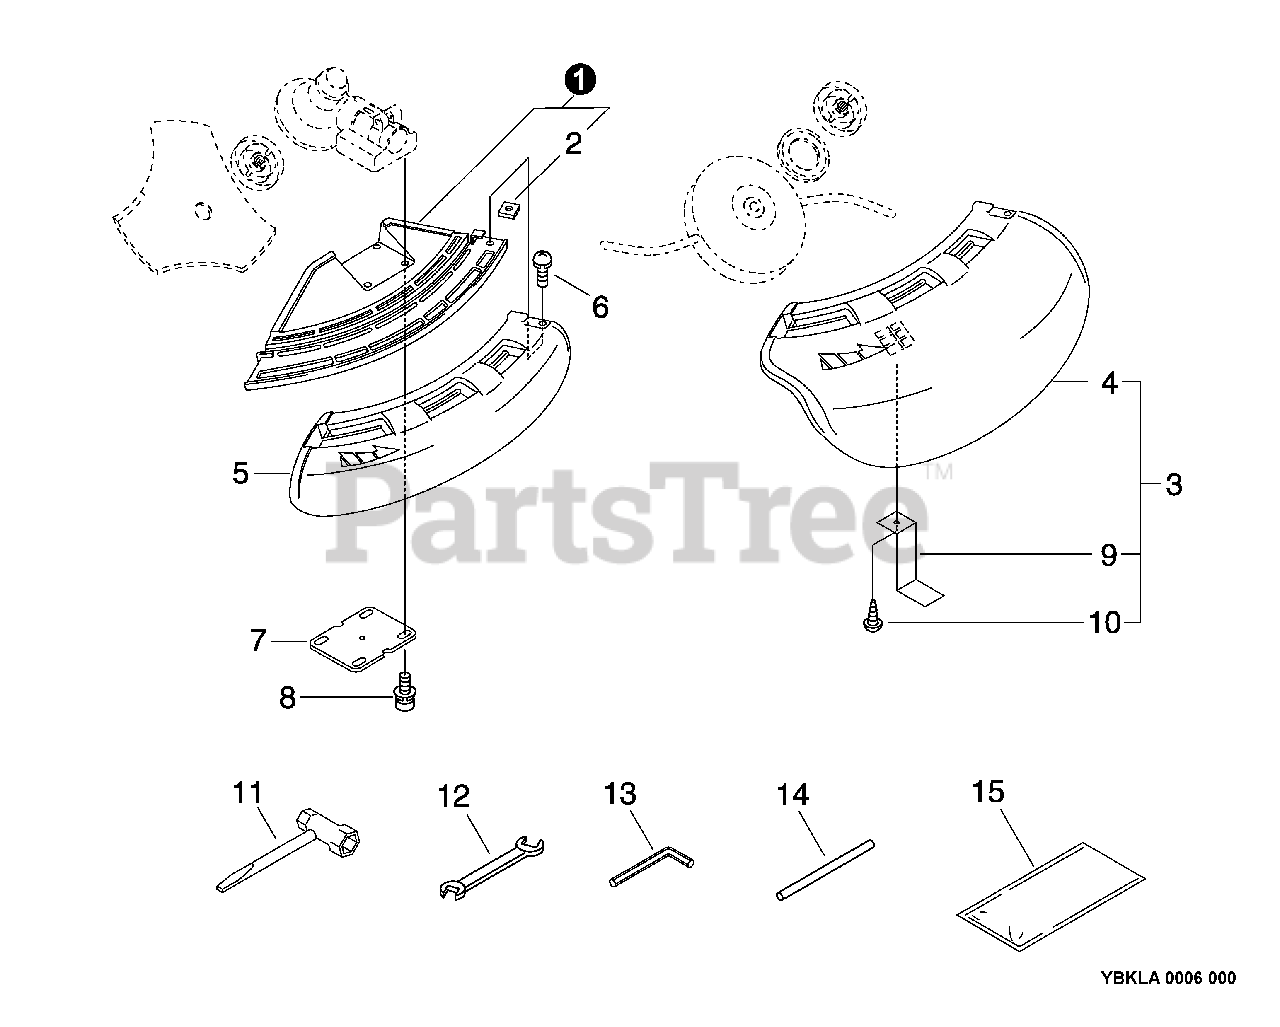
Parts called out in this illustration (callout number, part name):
1	BRACKET ASSY, SHIELD
2	NUT M5
3	DEBRIS SHIELD KIT
4	SHIELD, DEBRIS
5	SHIELD, BLADE
6	BOLT 5×22
7	PLATE, SHIELD
8	BOLT 5×25
9	CUTTER, LINE
10	SCREW, TAPPING 5×12
11	T-WRENCH 17x-19 L200
12	SPANNER 8×10
13	WRENCH, ALLEN 4 MM
14	TOOL, LOCKING 5×120 MM
15	BAG, TOOL
